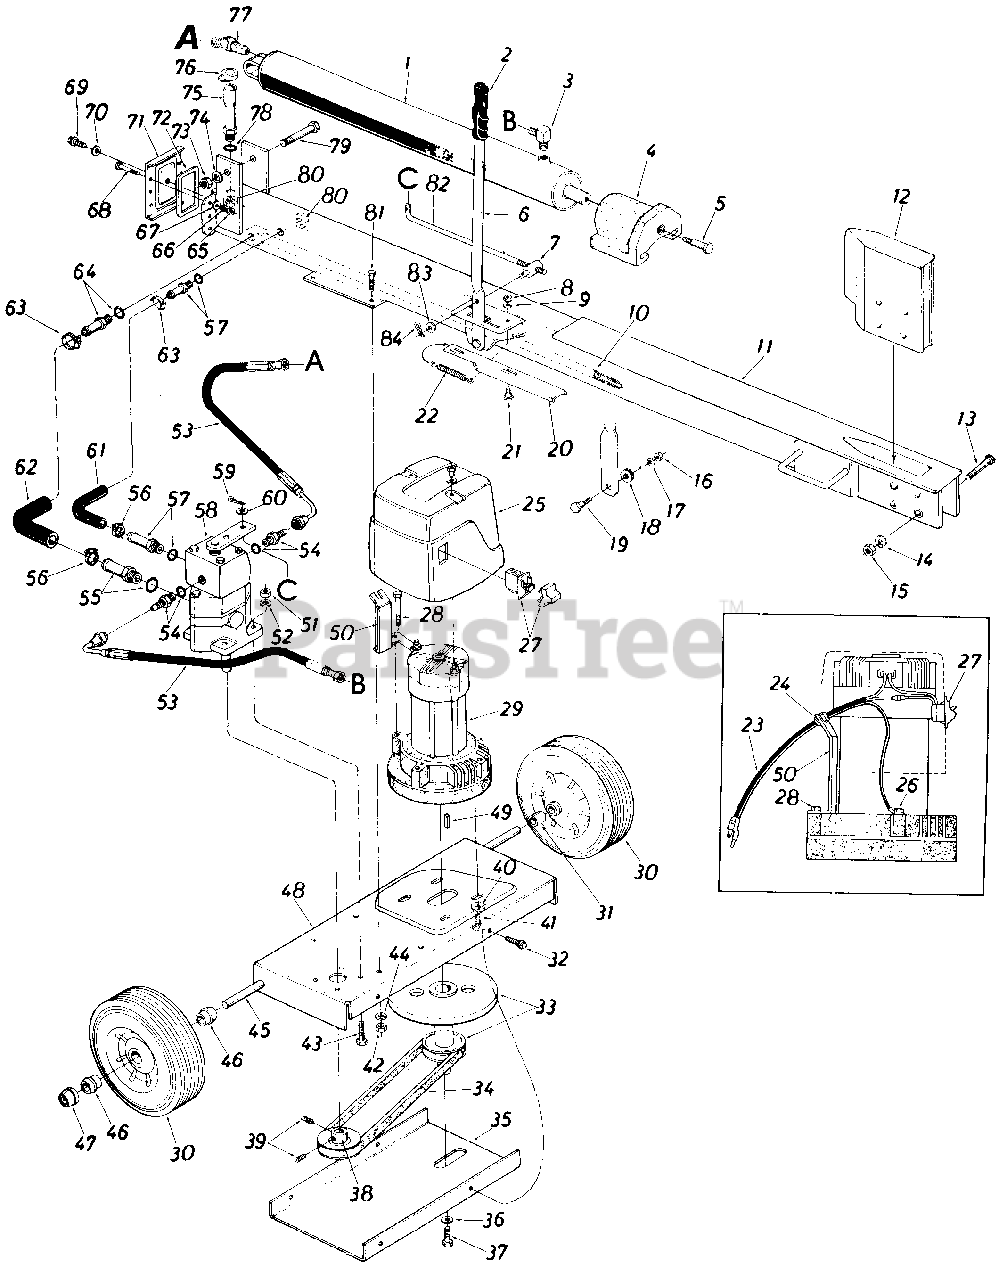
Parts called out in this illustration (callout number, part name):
1	2-1/2" Cyl. Ass'y. Comp.
2	Grip
3	90ø Elbow Adapter
4	Pusher Plate
5	Shoulder Bolt 5/8" Dia. x .660" Lg. 1/2-13 Thd.
6	Engagement Handle
7	Adjustment Ferrule
8	Hex Nut 5/16-18 Thd.*
9	L.-Wash. 5/16" I.D.*
10	Strainer Tube Ass'y.
11	Tank Ass'y . Comp.
12	Wedge Ass'y.
13	Hex Bolt 5/8-18 x 3.50" Lg. (Grade 5)
14	L.-Wash. 5/8" I.D.*
15	Hex Nut 5/8-18 Thd.
16	Hex Nut 3/8-1 Thd.*
17	L.-Wash. 3/8" I.D.*
18	Rubber Wash.
19	Shoulder Bolt .498 x .340
20	Engagement Brkt.
21	Shoulder Bolt .437" Dia. x.180" Lg.
22	Extension Spring .50" O.D. x 4.25" Lg.
23	Cord with Plug
24	Cord Restraint
25	Motor Shroud
26	Hex Wash. Hd. Scr. 8-32 x .38" Lg. (Green)
29	Electric Motor
30	Wheel Ass'y. Comp. 10.0" x 2.75
31	Sleeve .632" I.D. x .875" O.D. x .90" Lg.
32	Hex Wash. Hd. Self Tap. Scr. 1/4-20 x .50" Lg.
33	Motor Pulley & Flywheel Ass'y.
34	"V"-Belt (4L) 1/2" V x 29 " Lg.
35	Belt Cover
36	L.-Wash. 5/16" I.D.*
37	Hex Bolt 5/16-24 x .75" Lg. (Grade 5)
38	1/2 (4L) "V"-Pulley 5/8" I.D. x 3-1/2" O.D.
39	SetScr. 1/4-28 x.25" Lg.
40	Bell.-Wash. .345" I.D. x .88" 0.D.
41	Hex Bolt 5/16-18 x .50" Lg.*
42	Hex Nut 5/16-2 Thd.*
43	Hex Bolt 5/16-18 x 1.00" Lg.*
44	L.-Wash . 5/16 " I.D.*
45	Axle Shaft 5/8" Dia. x 25.5" Lg.
46	Flange Brg. w/Flats .631" I.D.
47	Push Cap 5/8" Dia. Rod
48	Frame - Motor
49	Sq. Key 3/16" x 3/16" x 1.50" Lg.*
50	Restraint Bracket
51	Hex Nut 5/16-18 Thd.*
52	L.-Wash. 5/16" I.D.*
53	High Pressure Hose
54	Adapter - or Boss to MJIC 9/16-18 to 7/16-20
55	Adapter 3/4" Tubing to 3/4 -16 M Boss
56	Hose Clamp 5/8" I.D.
57	Adapter 1/2" Tube 9/16-18 or M Boss
58	Valve Ass'y.
59	Cotter Pin 3/32" Dia. x .75" Lg.*
60	Fl.-Wash. .344" I.D. x .62" O.D. x .063
61	Return Hose.50" I.D.
62	Suction Hose .75" I.D.
63	Hose Clamp 1/4" I.D.
64	Adapter 1.0" Tube 1-1/16- -12 "O "-R ing
65	Hex Nut 5/16-18 Thd.*
66	L.-Wash. 5/16" I. D.*
67	Fl.-Wash .343" I.D. x .687" O.D. x .062
68	Hex Bolt 5/16-18 x 1.50" Lg.*
69	Hex Hd. Tap Scr. 5/16"
70	Gasket
71	End Plate
72	Gasket
73	Hex Nut 3/4" Thd.*
74	L.-Wash. 3/4" I.D.*
75	Filler Tube Ass'y.
76	Oil Fill Cap
77	45ø Male Adapter 7/16-20 MJ-1/4-18"
78	"O"-Ring.92" I.D. x 1.16" O.D. x .116 Dia.
79	Hex Bolt 3/4" x 4.0" Lg.
80	Hex Nut 11/16-1 Thd.
81	Hex Bolt 5/16-24 x 1.00" Lg. (Grade 5)
82	Engagement Rod 16.75" Lg.
83	Fl.-Wash. .344" 1. D. x .62" O.D. x .063
84	Hair Pin Cotter 5/16" Dia.
